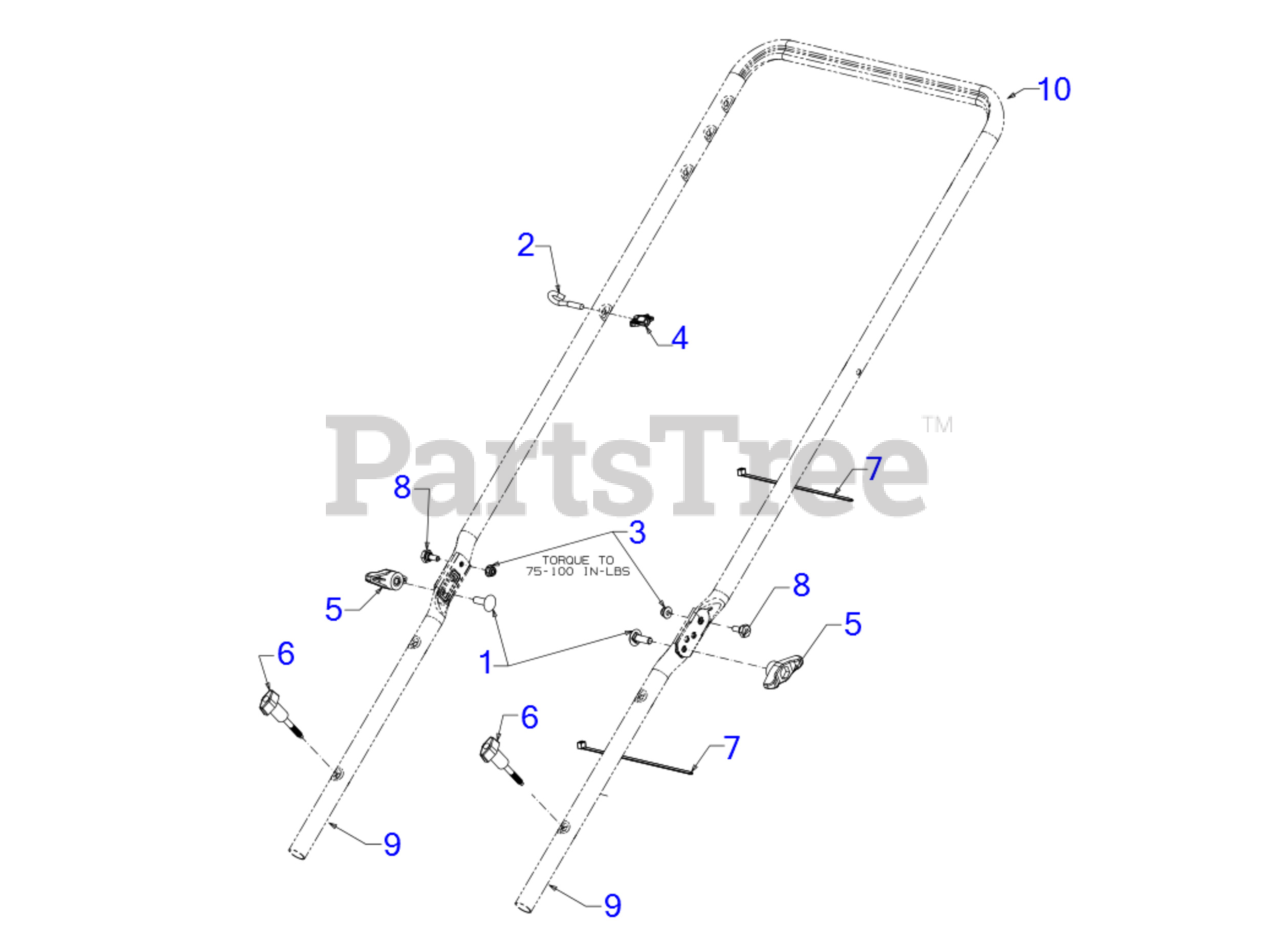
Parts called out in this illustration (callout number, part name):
1	SCREW 5/16-18 x 1.00 GR5
2	EYEBOLT 1/4-20
3	FLANGE LOCK NUT
4	HANDLE KNOB
5	WING KNOB 5/16-18
6	WING KNOB 1/4-20
7	7" CABLE TIE
8	SHOULDER SCREW
9	LOWER HANDLE
10	NON ADJUST UPPER HANDLE
